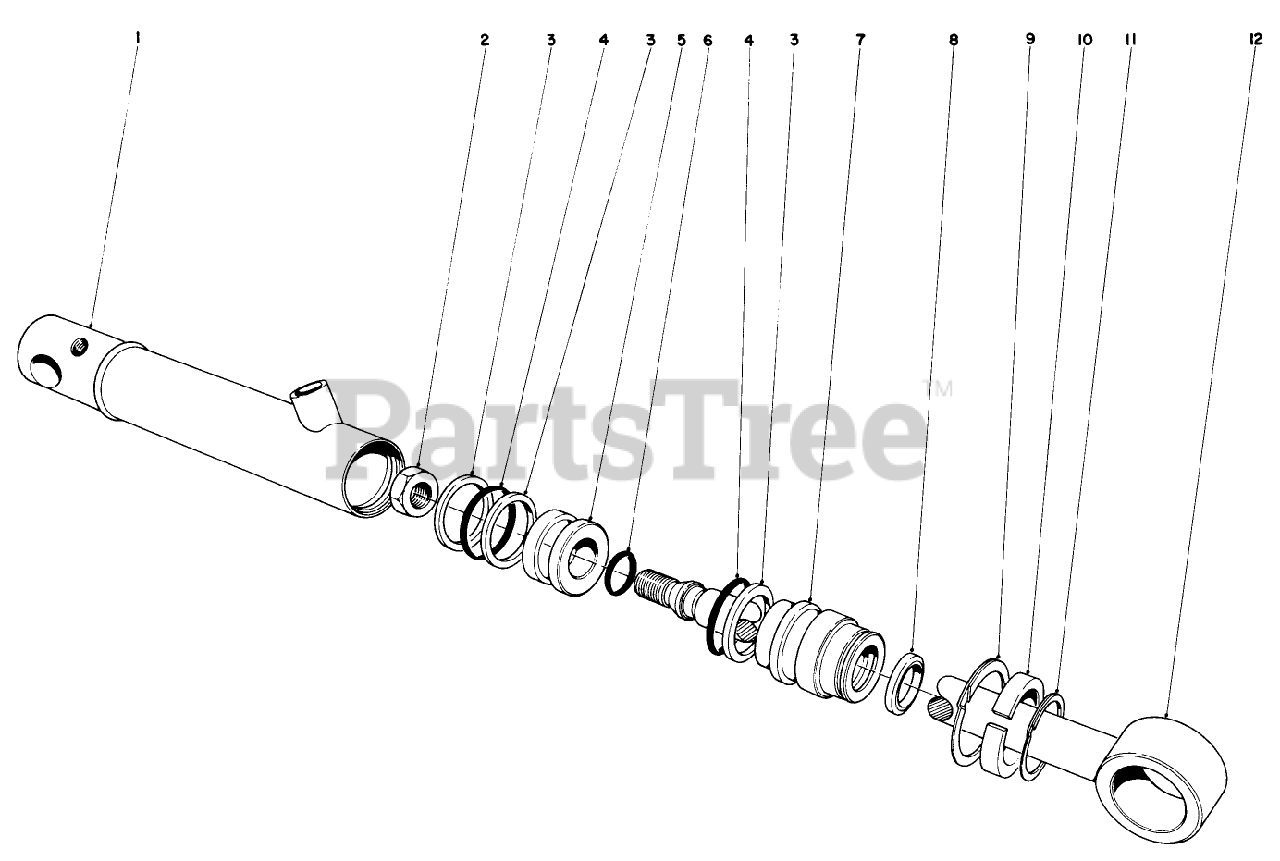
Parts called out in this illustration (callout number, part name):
1	Tube Assembly
2	Nut
3	Washer-Backup
4	O-Ring
5	PISTON
6	O-Ring
8	0-Ring
9	Leather
10	Dust Seal
11	RING-RETAINING
12	SHAFT W/CLEVIS
